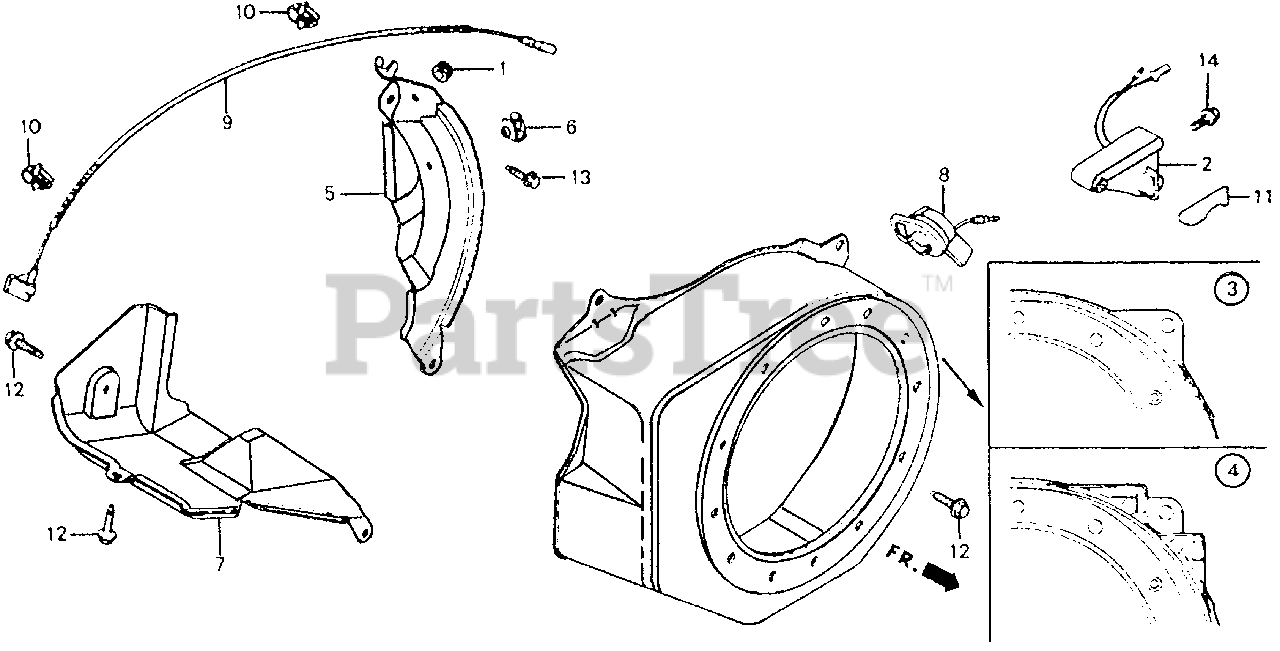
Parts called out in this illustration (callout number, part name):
1	GROMMET, ADJUSTING COVER
2	ALERT UNIT, OIL
4	COVER, FAN *R8* (OIL ALERT) (BRIGHT RED)
5	PLATE, SIDE (OIL ALERT)
6	CLAMP, CORD
7	SHROUD
9	WIRE, STOP SWITCH
9	WIRE, STOP SWITCH (370MM)
10	HOLDER, STOP SWITCH WIRE
11	MARK, OIL ALERT (EXTERNAL)
12	BOLT, FLANGE (6X12) (CT200)
13	BOLT, FLANGE (6X12) (CT200)
13	BOLT, FLANGE (6X20) (CT200)
14	BOLT, FLANGE (6X8)
